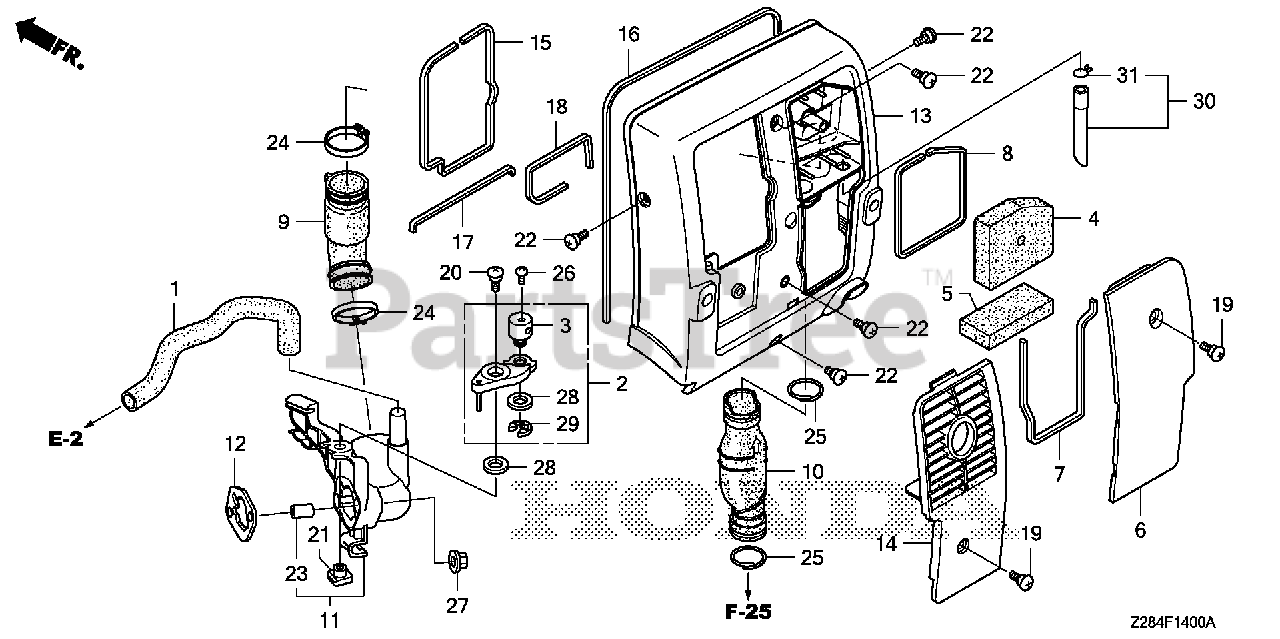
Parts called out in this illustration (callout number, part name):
1	TUBE, BREATHER
2	LEVER ASSY., CHOKE
3	HOLDER, CABLE
4	ELEMENT, AIR CLEANER
5	FILTER (OUTER)
6	COVER, AIR CLEANER *NH314* (CONDUCT GRAY)
7	SEAL A, AIR CLEANER COVER
8	SEAL C, AIR CLEANER COVER
9	TUBE, AIR CLEANER CONNECTING
10	TUBE, RESONATOR
11	JOINT, AIR IN.
12	GASKET, AIR IN. JOINT
13	COVER, RR. *NH314* (CONDUCT GRAY)
14	COVER, MUFFLER PROTECTOR *NH314* (CONDUCT GRAY)
15	SEAL, RR. COVER (565MM)
16	SEAL, RR. COVER (UPPER)
17	SEAL, RR. COVER (LOWER)
18	SEAL, RR. COVER (261MM)
19	SCREW, SPECIAL (6X16)
20	SCREW, SPECIAL (6X12)
21	NUT, SPECIAL (6MM)
22	SCREW, SPECIAL (6X15)
23	COLLAR, IN. JOINT
24	CLAMP, HOSE
25	CLIP, AIR CLEANER TUBE
26	SCREW, PAN (4X6)
27	NUT, FLANGE (6MM)
28	WASHER, PLAIN (6MM)
29	E-RING (5MM)
30	TUBE ASSY., AIR CLEANER
31	CLIP, BREATHER TUBE
